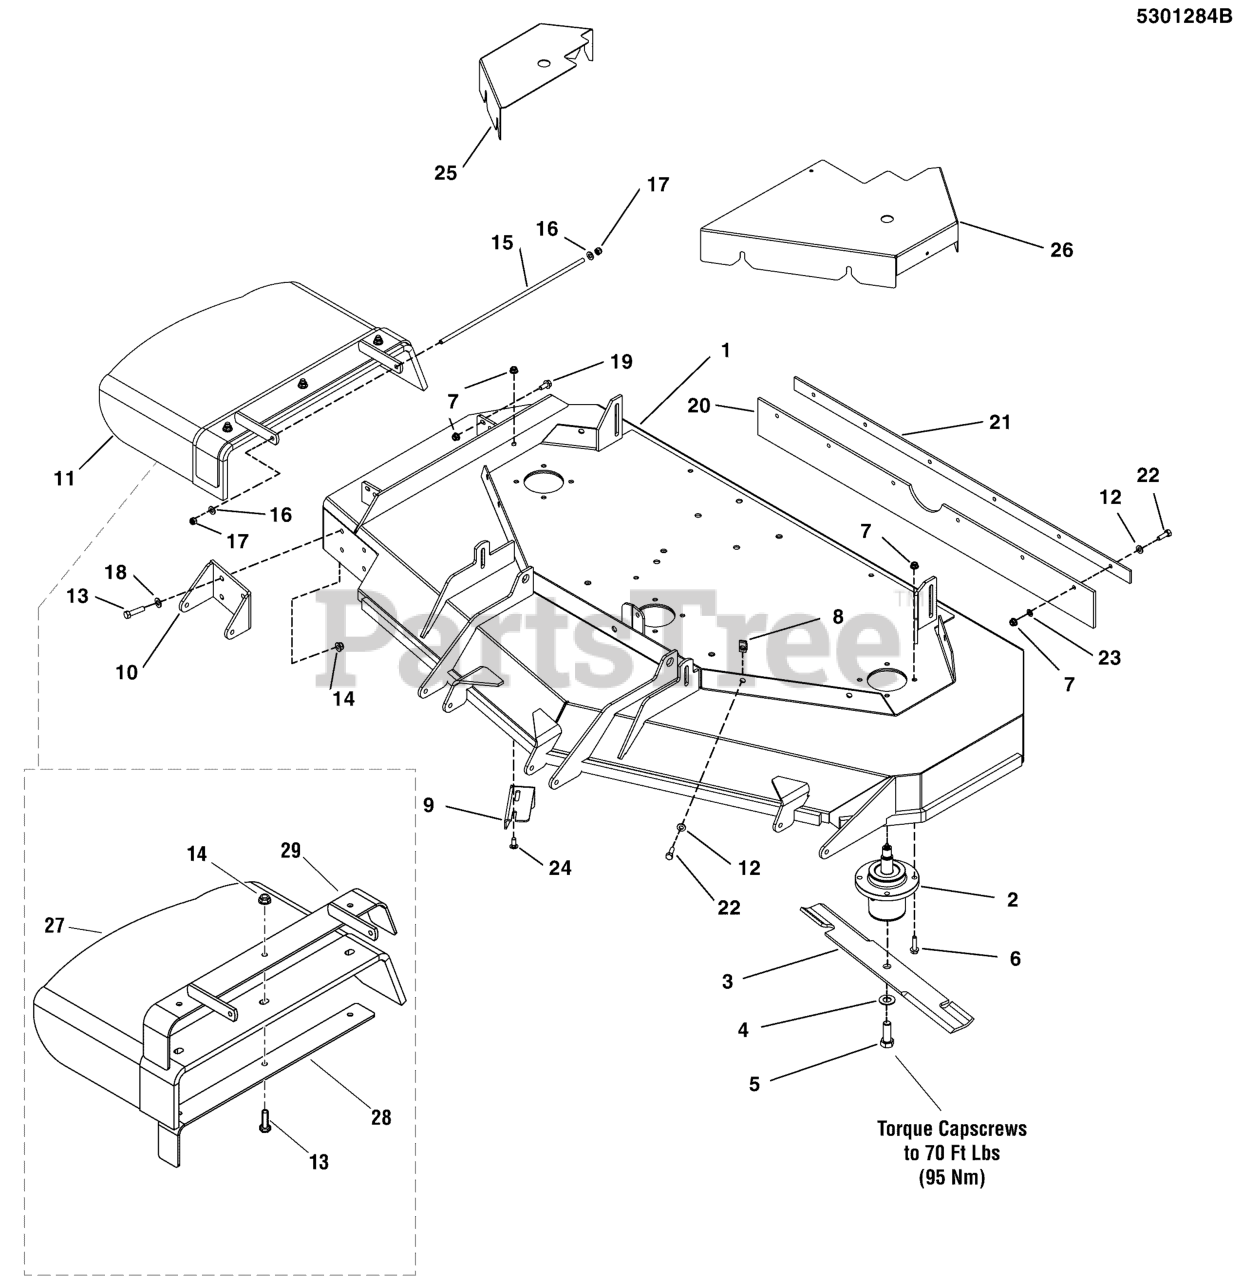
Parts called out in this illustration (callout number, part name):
1	DECK SHELL W/ DECALS, IS1500ZX 61
2	SPINDLE, ASSM, ALUMINUM - 5.25
3	BLADE SET, 61 DECK (3)
4	WASHER, BLADE BOLT, 9/16" F436, CZ
5	BOLT, 5/8-11 X 1-3/4 GD8
6	BOLT, 5/16-18 X 1-1/4" FLANGE
7	NUT, 5/16-18 HEX NYLOCK FLANGE NUT
8	BODY CLIP, 5/16-18-7GA MATERIAL
9	PLATE, DEFLECTOR - BLK
10	PLATE, BRACKET, ANTI SCALP, RH - 61 -RED
11	PURCHASE INDIVIDUAL REPLACEMENT PARTS
12	WASHER, 5/16" SAE
13	BOLT, 3/8-16 X 1-1/2" GD5 CZ
14	NUT, 3/8 - 16 HEX NYLOCK FLANGE
15	ROD, MOUNT, CHUTE, 61, CZ
16	WASHER, 5/16" SAE
17	NUT, 5/16-24 HEX NYLON LOCK
18	WASHER, 3/8 SAE
19	BOLT, 5/16-18 X 3/4 GD5
20	FLAP, STRIPER, 61 DECK
21	PLATE, SUPPORT - BLK
22	BOLT, 5/16-18 X 1" GRD5 YZ
23	5/16" PUSH-ON NUT RETAINER, STL, CZ
24	BOLT, 5/16-18 X 3/4, CARRIAGE, GD5, CZ
25	GUARD, 61", RH - RED
26	GUARD, 61, LH - RED
27	CHUTE, DISCHARGE, BEND RUBBER (SV)
28	SUPPORT, DISCHARGE CHUTE, 61/72 - BLK
29	WELD, FRAME CHUTE, 61 - BLK
